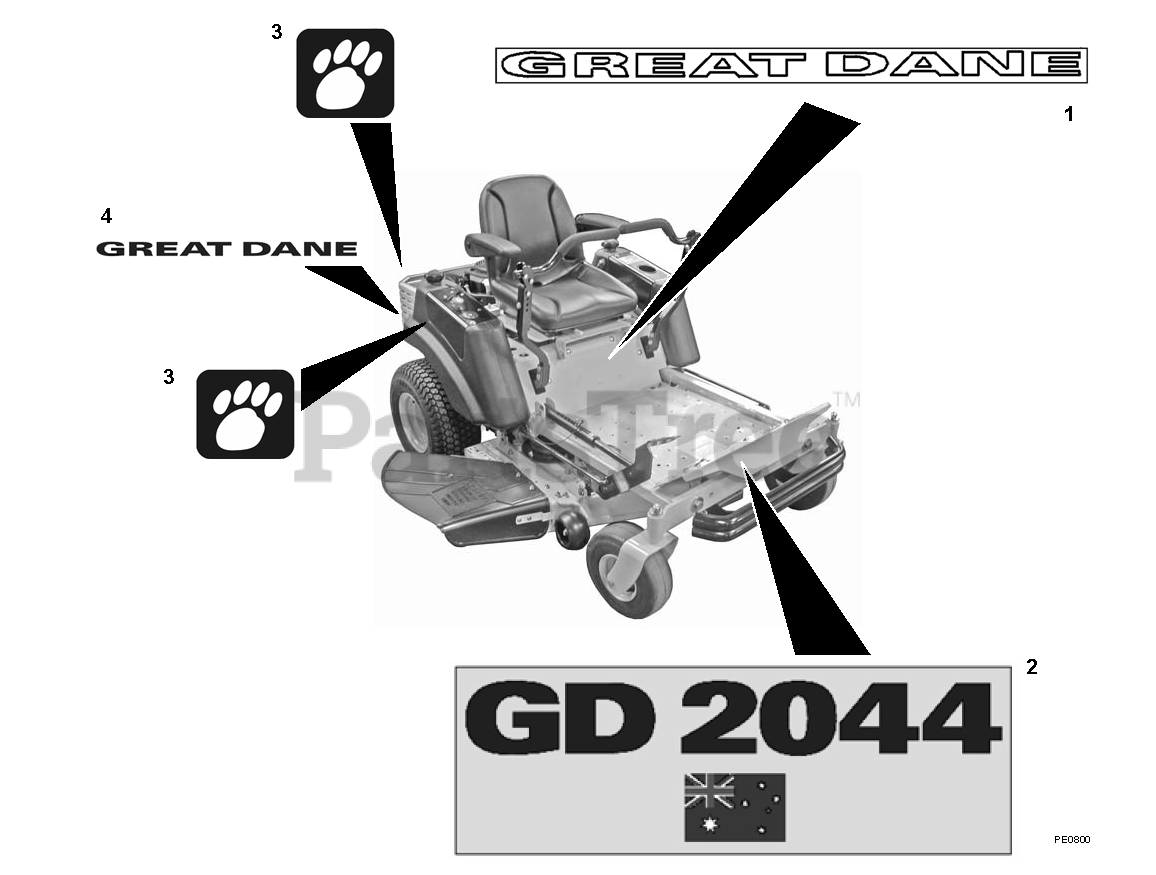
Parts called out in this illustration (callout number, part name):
1	DECAL, GREAT DANE
2	DECAL, GD 1840
3	DECAL, PAW PRINT
4	DECAL, GREAT DANE
